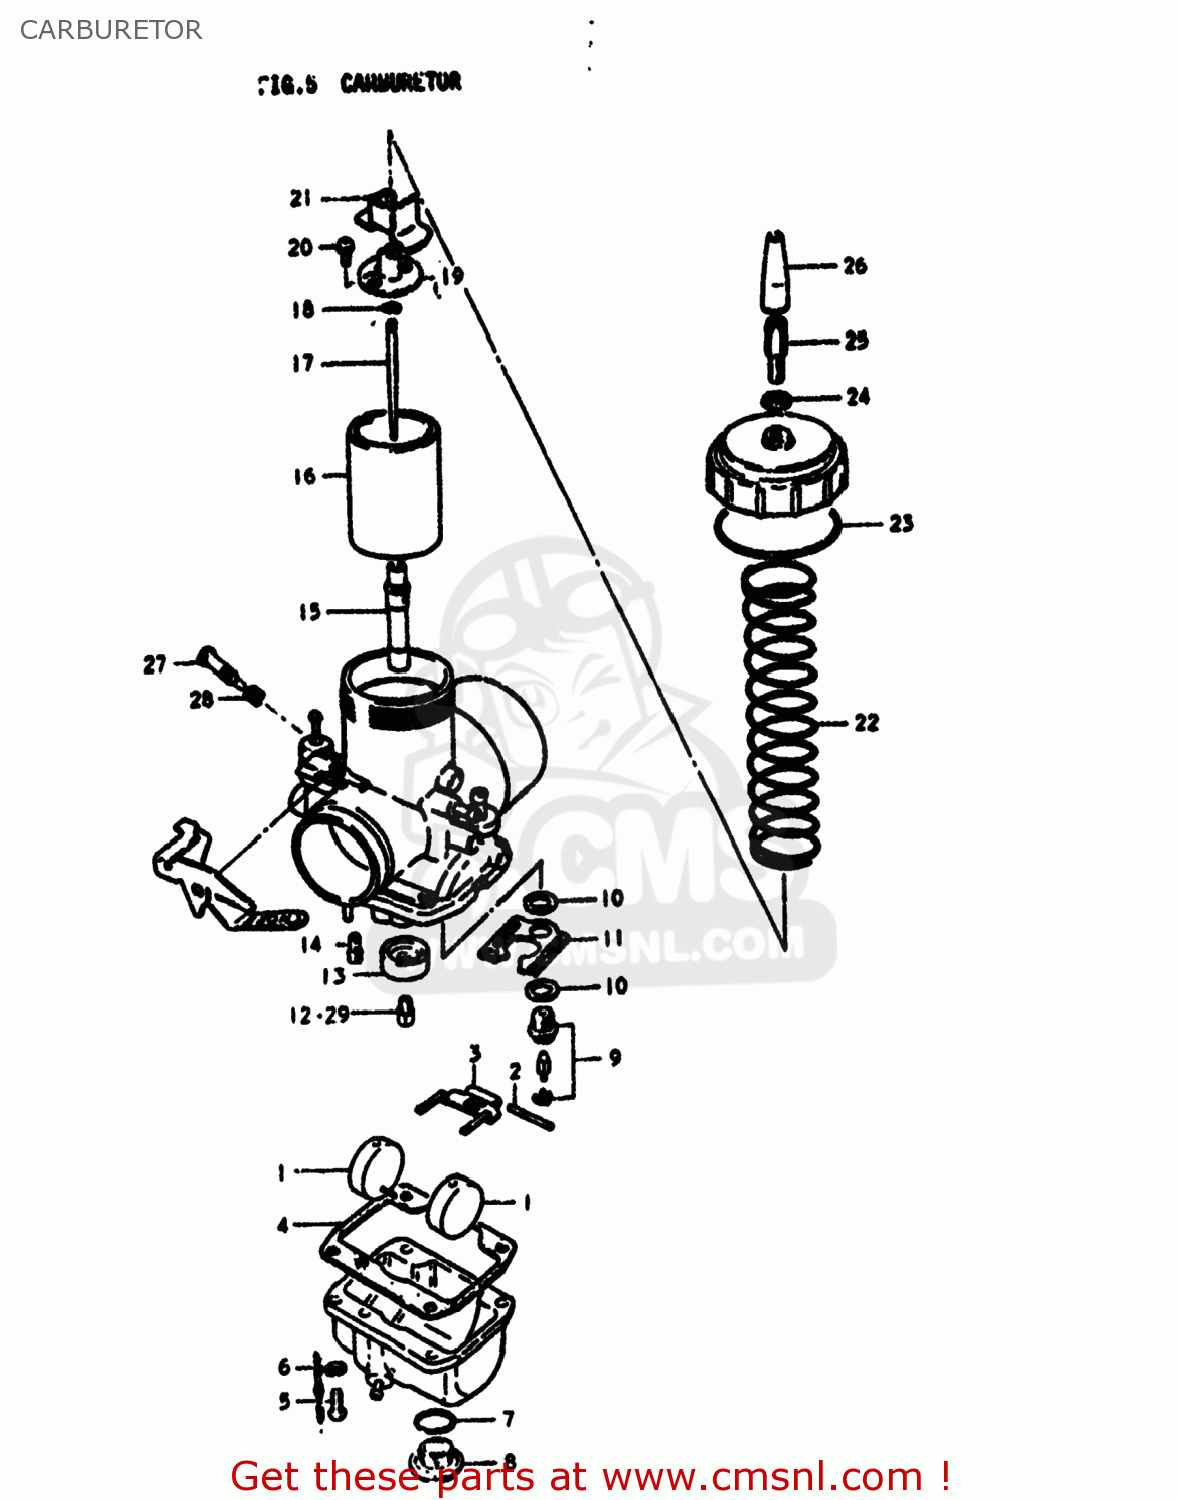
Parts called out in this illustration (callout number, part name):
1	FLOAT
2	PIN,FLOAT
3	ARM,FLOAT
4	GASKET,FLOAT CAHMBER (NAS)
5	SCREW
6	LOCK WASHER
7	O-RING
8	PLUG
9	VALVE ASSEMBLY,NEEDLE
10	GASKET,MAIN JET HOLDER (NAS)
11	PLATE
12	JET
13	RING
14	JET,PILOT(50)
15	JET,NEEDLE
16	VALVE,THROTTLE
17	JET,NEEDLE(6FJ6-3)
18	CLIP
19	CONNECTOR
20	SCREW
21	COVER,HOLDER
22	SPRING,THROTTLE VALVE RETURN
23	GASKET,MIXING CHAMBER (NAS)
24	NUT
25	ADJUSTER,CABLE
26	CAP,CABLE ADJUSTER
27	SCREW,PILOT AIR
28	SPRING
29	JET
